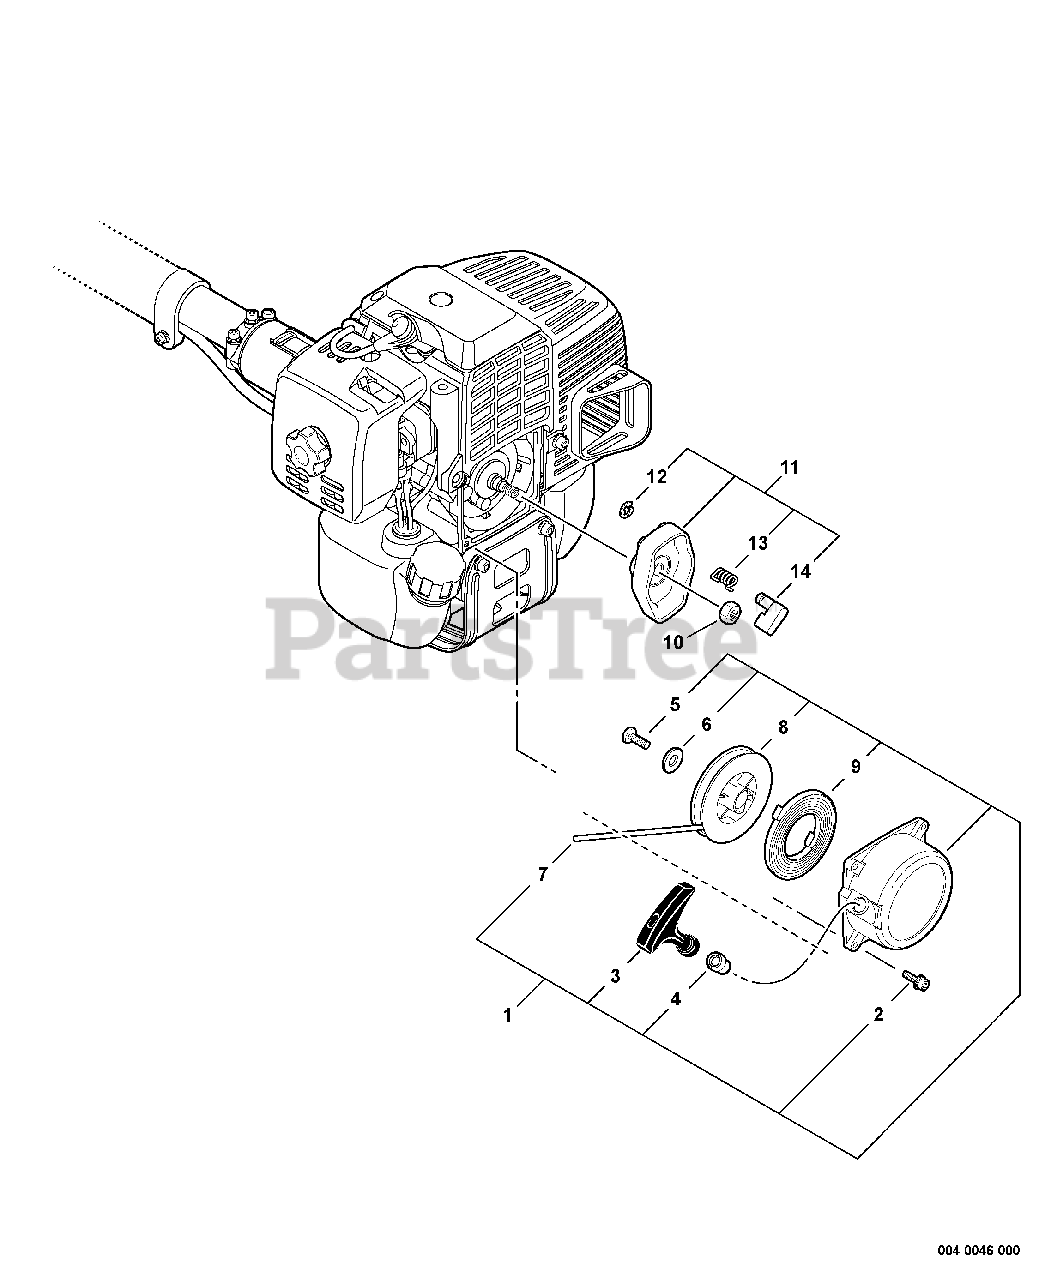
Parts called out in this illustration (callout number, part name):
1	STARTER ASSY
2	BOLT 4×14
3	GRIP, STARTER
4	GUIDE, ROPE
7	ROPE, STARTER 4.0×880
8	REEL, ROPE
9	SPRING, RECOIL
10	NUT 8×1.25
11	PAWL ASSY, STARTER
12	E-RING 4
13	SPRING, RETURN
14	PAWL, STARTER
